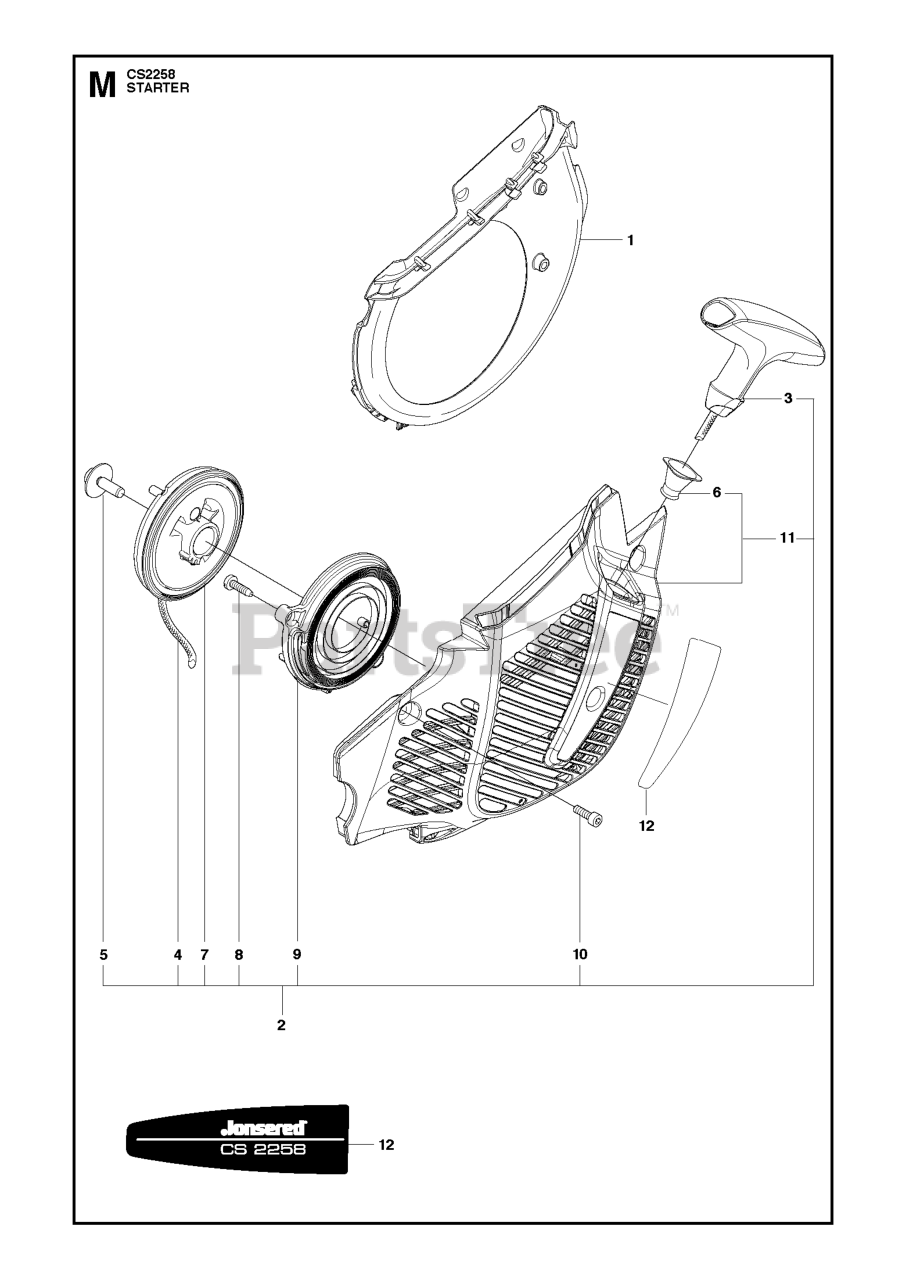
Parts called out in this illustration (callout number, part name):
1	COOLING AIR CONDUCTOR
2	STARTER ASSY
3	STARTER HANDLE
4	STARTER ROPE
5	SCREW
6	SLEEVE
7	STARTER PULLEY ASSY
8	SCREW
9	SPRING CASSETTE ASSY
10	SCREW.CIHPANMO M5X19 10.9
11	STARTER HOUSING
